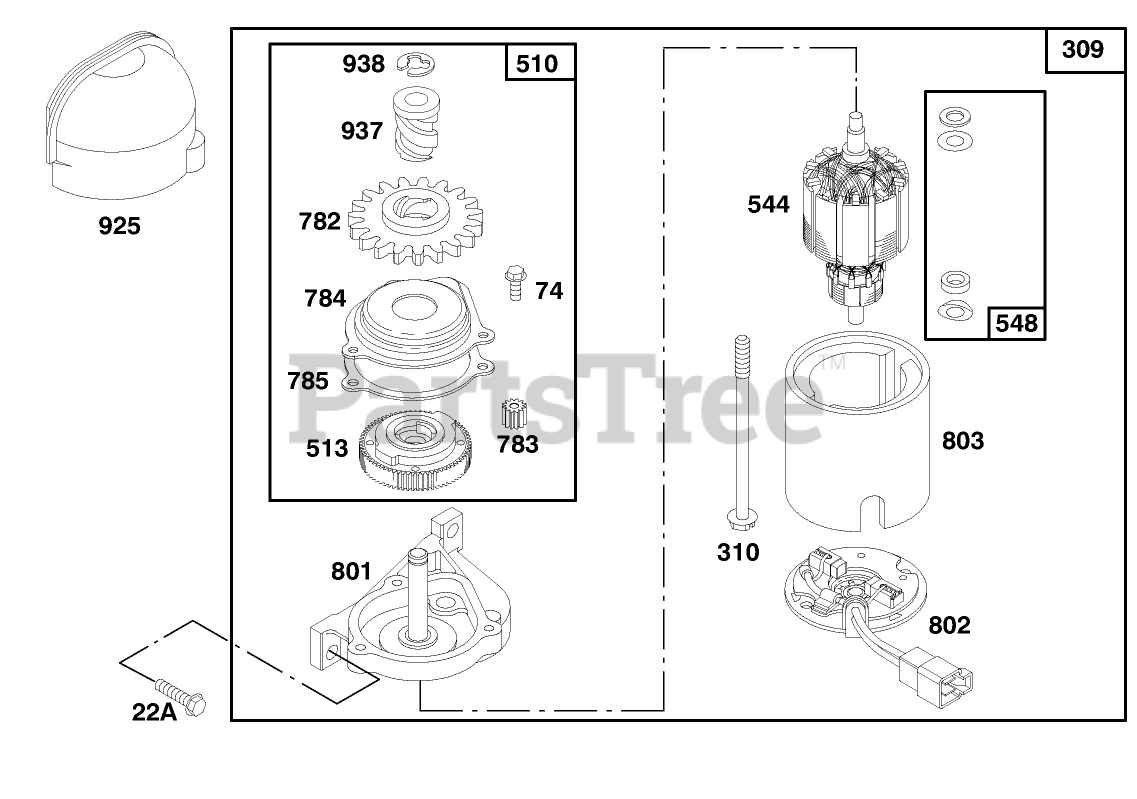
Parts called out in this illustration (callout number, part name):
510	DRIVE SET
513	CLUTCH - STARTER
548	RETAINER - SPRING
782	GEAR - STARTER
925	COVER - STARTER
938	RETAINER - LOCK
